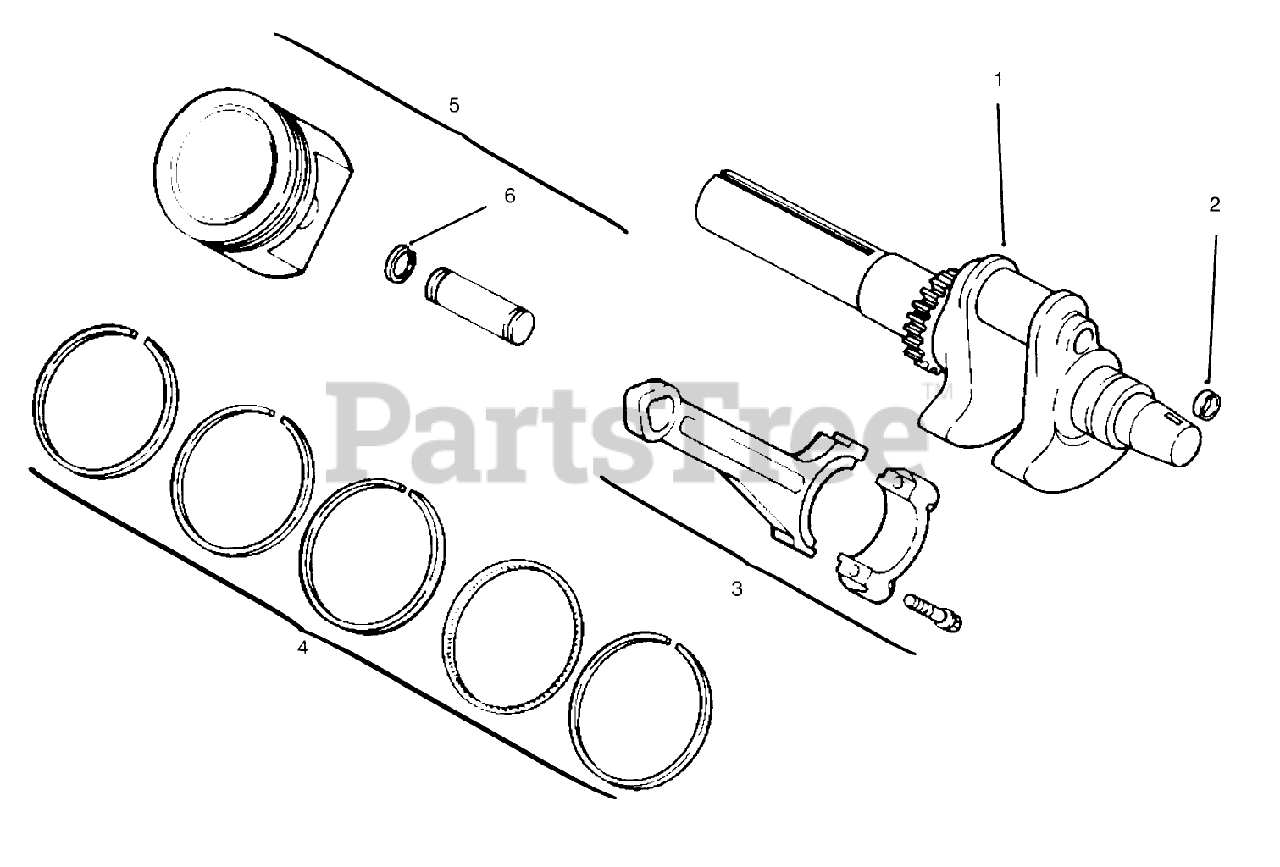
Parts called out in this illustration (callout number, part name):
1	Crankshaft
2	Plug-Cup
3	Connecting Rod STD
4	Ring Set(Std.)
5	Piston w/Ring Set (Std.) (Incl. Ref. #4-6)
6	Retainer-Piston Pin
